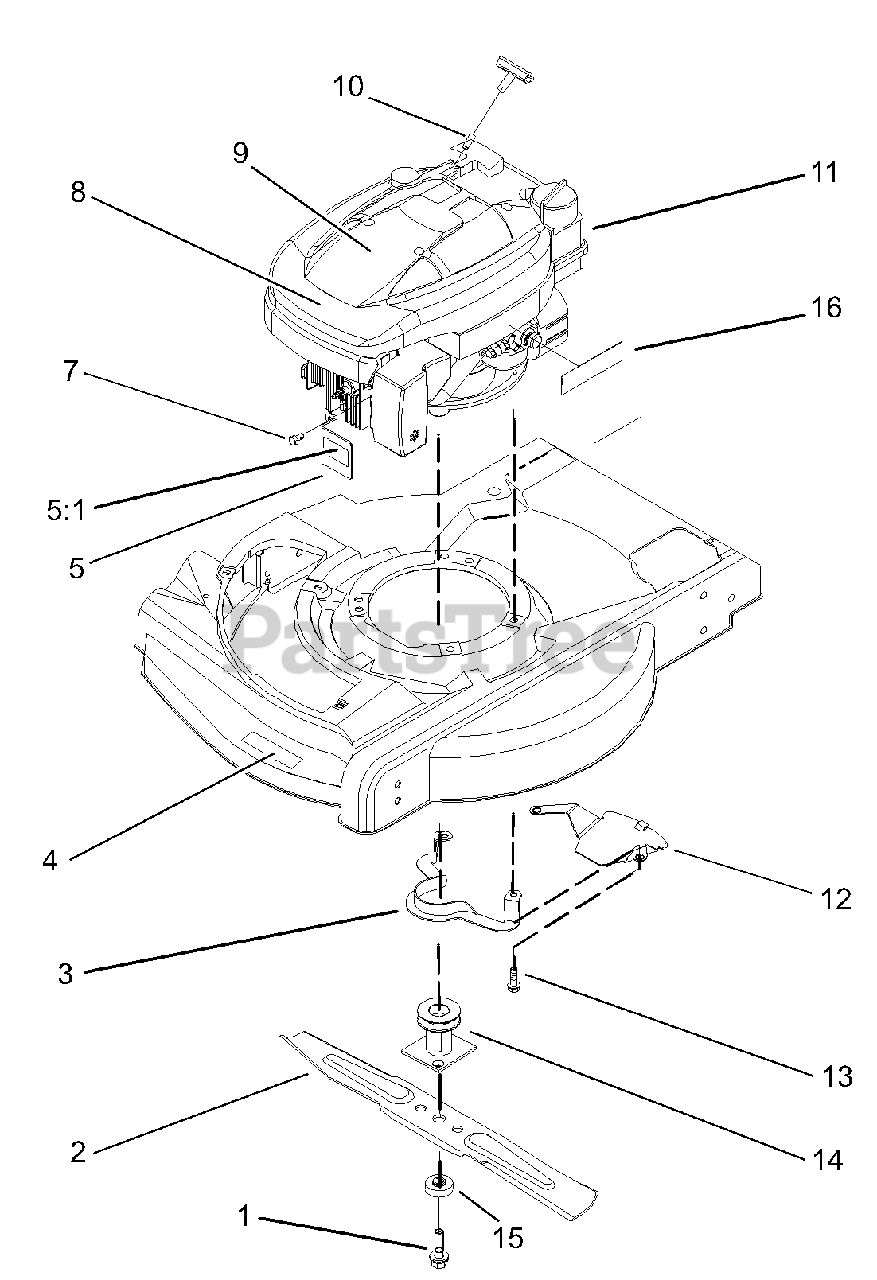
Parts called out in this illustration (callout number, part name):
1	Bolt-Blade,Sems
3	Guide-Belt
4	Decal-Deck
5	Muffler Guard ASM (only on: 10356, 10358)
5	Muffler Guard ASM (only on: 10359c)
5:1	Decal-Surface Hot, International (only on: 10359c)
5:1	Decal-Surface, Hot (only on: 10356, 10358)
7	Screw-HWH
8	Applique
9	Decal-Recoil, Lb
10	Stop-Rope
12	Shield-Grass
13	Screw-Taptite W/Patch
14	Driver-Blade, ASM
16	Decal-Primer (only on: 10359c)
